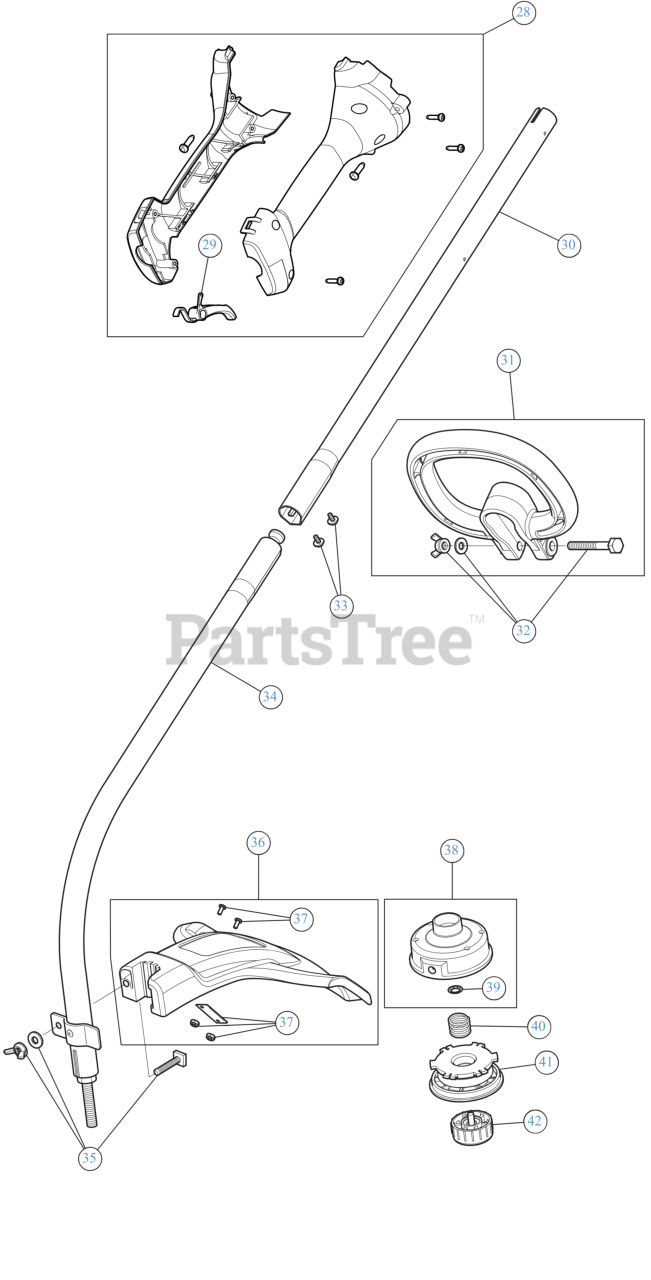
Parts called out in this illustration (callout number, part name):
28	THROTTLE GRIP ASSEMBLY
29	THROTTLE TRIGGER
30	UPPER BOOM ASSEMBLY
31	HANDLE
32	HANDLE HWD
33	SCREW 8-32X3/8
34	LOWER BOOM ASSEMBLY
35	BLADE GUARD MOUNTING HARDWARE
36	GUARD ASSEMBLY
37	BLADE ASSEMBLY CUTOFF
38	REEL:OTR W/RET
39	RETAINER .625 OD 2
40	SPRING-SPOOL
41	REEL-INNER SPOOL
42	BUMP HEAD KNOB ASSEMBLY
